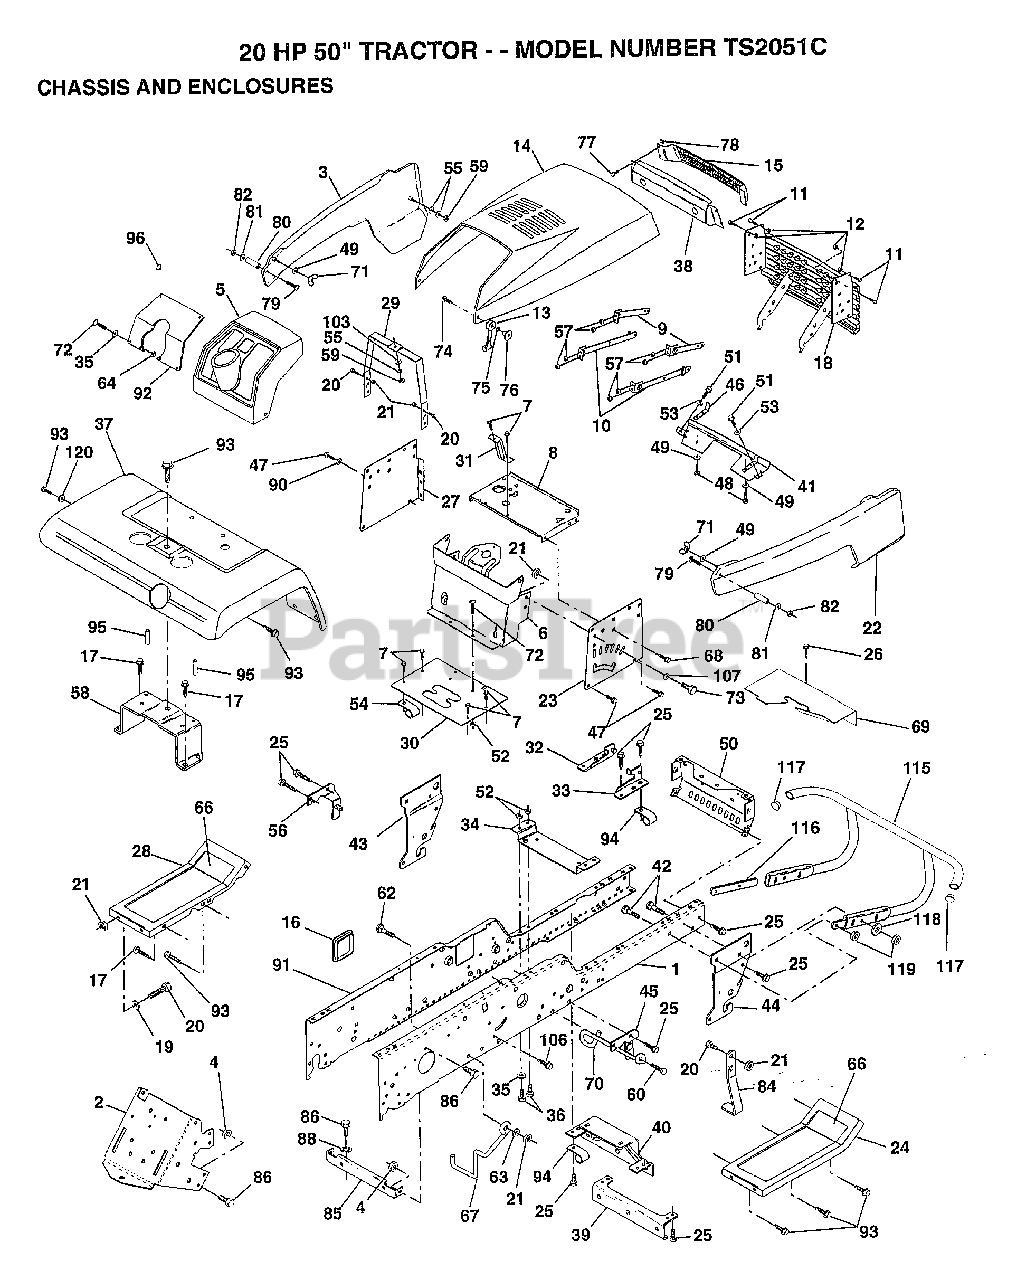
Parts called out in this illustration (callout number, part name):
2	DRAWBAR GT
4	NUT.7/16
5	DASHBOARD BLACK
6	DASH ASM LOWER
7	SCREW
8	SUPPORT BATRY VGT
12	NUT
13	HOOD LATCH T
15	LENS LT
16	COVER ACCESS
17	SCREW
18	GRILLE.ASM.PNT.YP
19	WASHER
20	BOLT
21	NUT
22	PANEL SIDE RH
25	SCREW
26	SCREW
29	SUPPORT ASS'Y
30	SADDLE SLKSCRNED
31	BRACE.SUPT.STRG
32	BRACKET ASM FRAME
33	BRACKET ASM FRAME
34	BRACKET.ENG.SUPT.
35	WASHER
36	BOLT
37	FENDER.PNT.
39	BRACKET.AXLE.FRT.
43	BRACKET.SUS.FT.LH
44	BRACKET.SUS.FT.RH
47	SCREW LT
48	SCREW
49	WASHER
50	BRACKET.CHASSIS.
51	SCREW HEX CRT
52	NUT
53	WASHER
54	"CLIP,INSULATOR"
55	WASHER PM
57	NUT
58	BRKT.ASM.FENDER
60	SCREW
61	SCREW
62	RETAINER M
66	FOOTREST PAD
68	SCREW LT
69	SHIELD.HEAT.MUF
70	GUIDE.BELT.MID.SP
72	SCREW
73	BOLT
74	SCREW
75	LOCKWASHER
76	WELDNUT
78	"""J"" FASTENER LT"
79	SCREW
80	SPACER LT
81	WASHER
84	STOP.OVER.CENTER
86	BOLT
90	LOCKWASHER
92	PLATE YP SLKSCR
93	SCREW LT
94	CLIP GTV
95	NUT-PUSH YT
96	PLUG-DASH T
98	BRACKET SKID CHAS
99	ROD BYPASS
101	SCREW LT
103	LOCKWASHER
104	LOCK BYPASS BRKT
105	SCREW LT
107	WASHER
115	BUMPER.ASM.W/PY
116	BRACKET.EXT.BUMP.
117	PLUG.PLASTIC
118	WASHER
120	WASHER HYT
